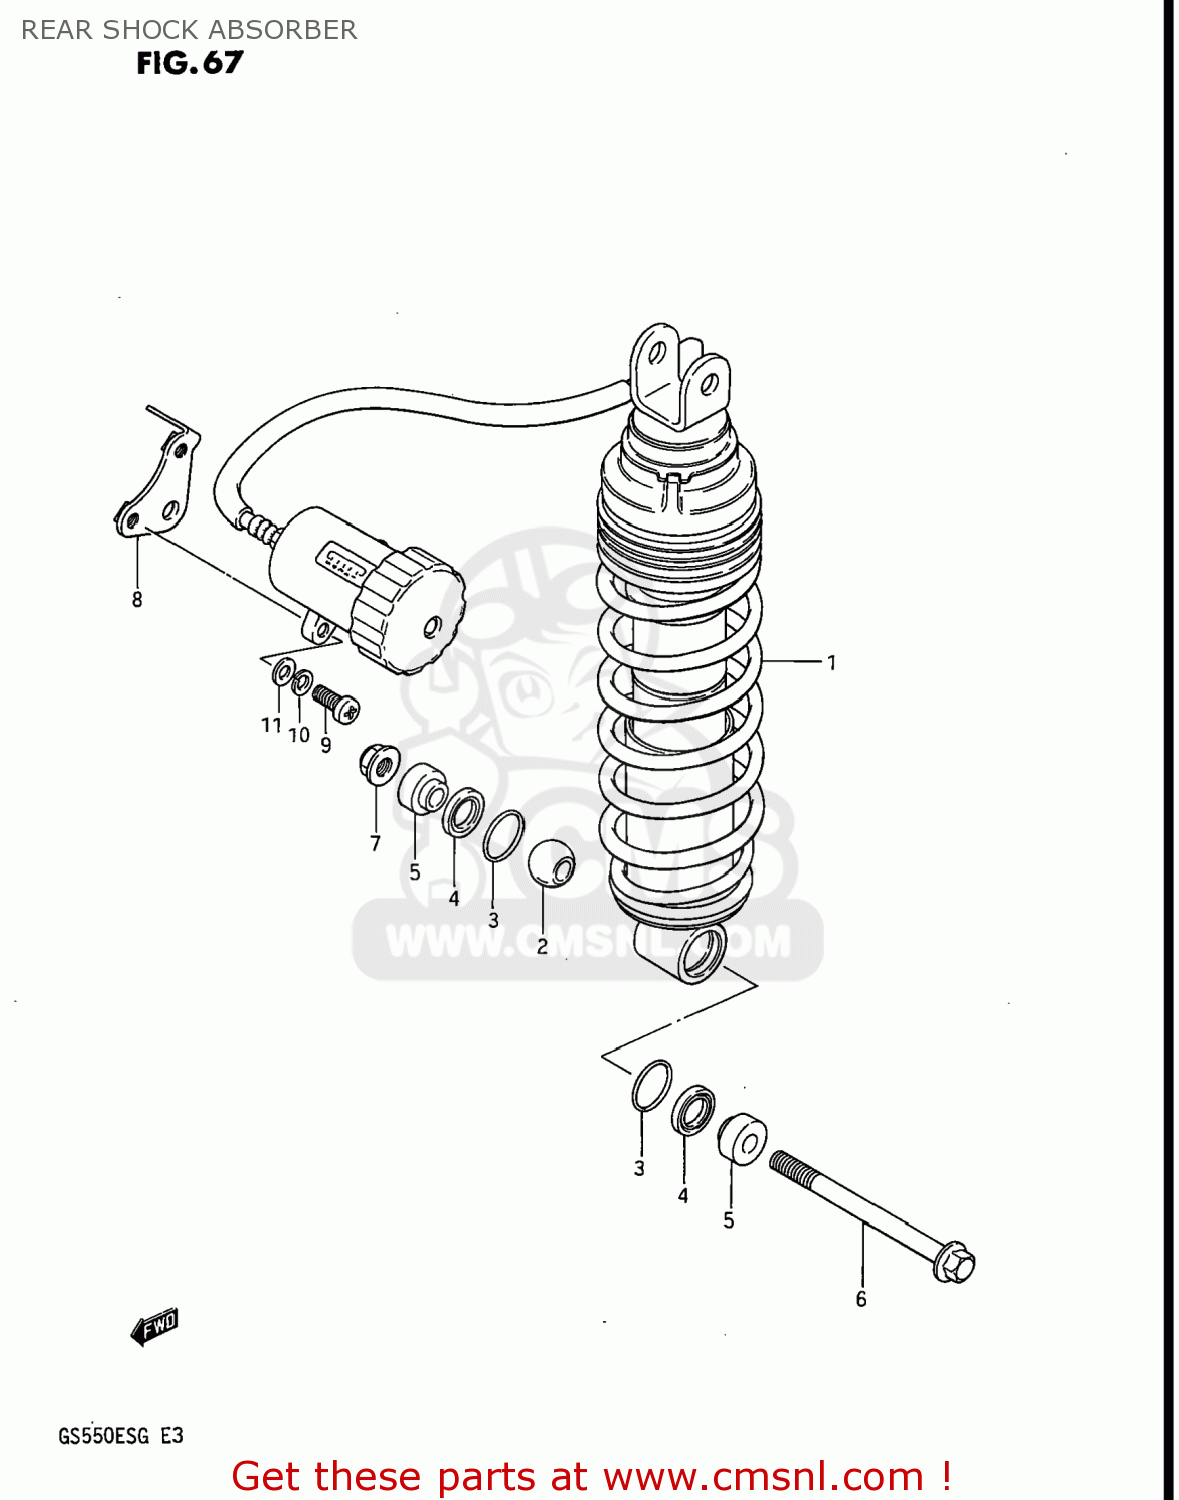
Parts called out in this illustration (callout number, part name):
1	ABSORBER ASSEMBLY,REAR SHOCK
2	BEARING,REAR SHOCK ABSORBER
3	RING
4	SEAL,DUST
5	COLLAR
6	BOLT(10X115)
7	NUT
8	BRACKET,RESERVOIR TANK
9	SCREW
10	WASHER,LOCK
11	WASHER
